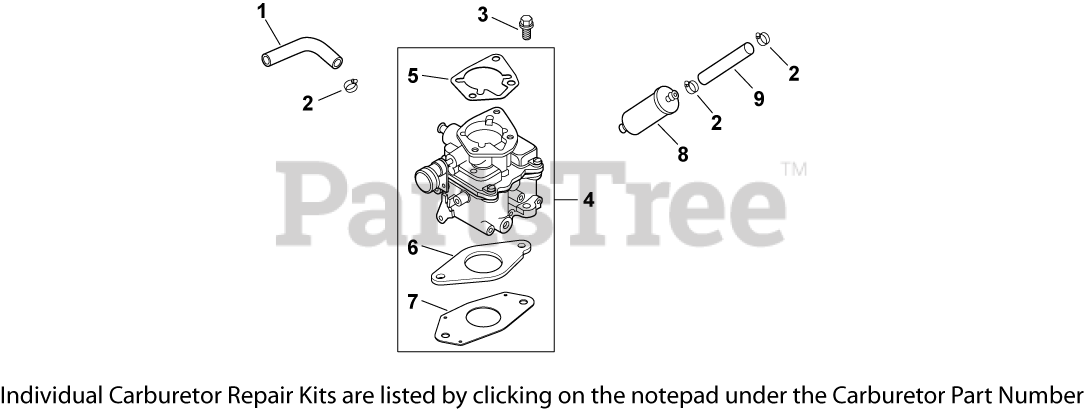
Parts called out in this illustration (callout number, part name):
1	HOSE,LW PERM.FUEL 24.00"-USE 25 111 81-S
2	CLAMP, HOSE (KM)-USE 25 237 31-S
3	SCREW, FLG M6X1.0X30
4	KIT, CARBURETOR W/GASKETS-KSF
5	GASKET, AIR CLEANER BASE
6	GASKET, CARBURETOR
7	GASKET, CARBURETOR
8	FILTER, FUEL
9	LINE, FUEL 11"
